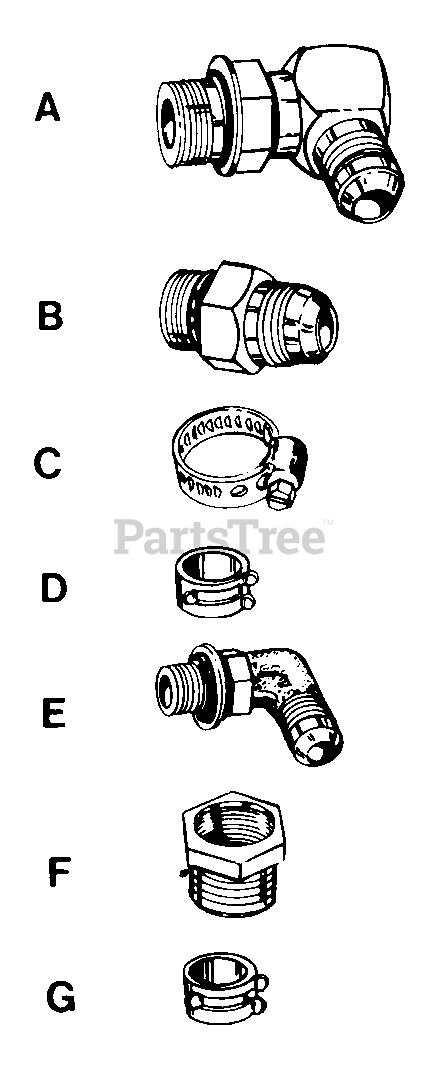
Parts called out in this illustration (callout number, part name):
A	7/8-14 SAE Boss to 3/4-16 JIC.
B	Boss to Male JIC.
C	Hose Clamp 1.25 x .66 I.D>
D	Hose Clamp .406" Dia.
E	1/2-40 SAE Boss to 1/2 20
F	Pipe Reducer 1/2-14 to 3/8 18 NPT
G	Hose Clamp .37" Dia.
